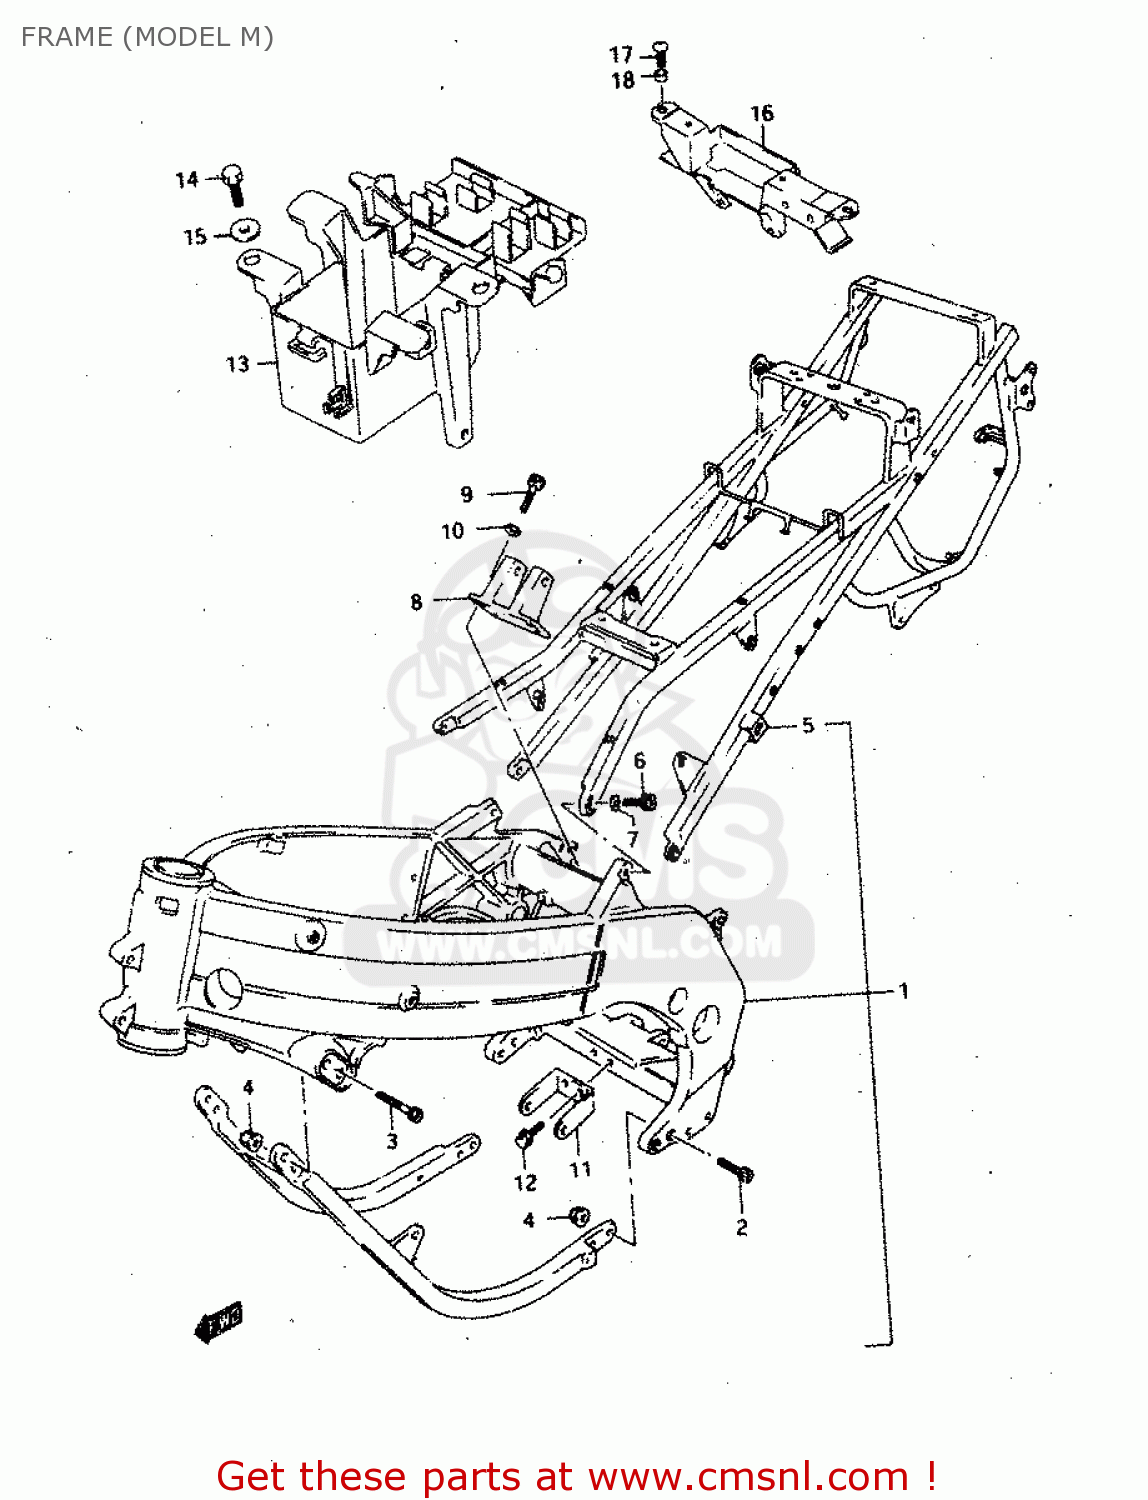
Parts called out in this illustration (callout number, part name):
1	FRAME SET
2	BOLT
3	BOLT
4	NUT
5	SEAT RALE
6	BOLT
7	WASHER
8	BRACKET,R.C.U.
9	BOLT(8X25)
10	WASHER
11	PLATE, ENGINE MOUNTING
12	BOLT
13	HOLDER, BATTERY
14	BOLT
15	WASHER
16	HOLDER, ELECTRIC PARTS
17	SCREW 6X12
18	SPACER (6.1X9X3.8)
